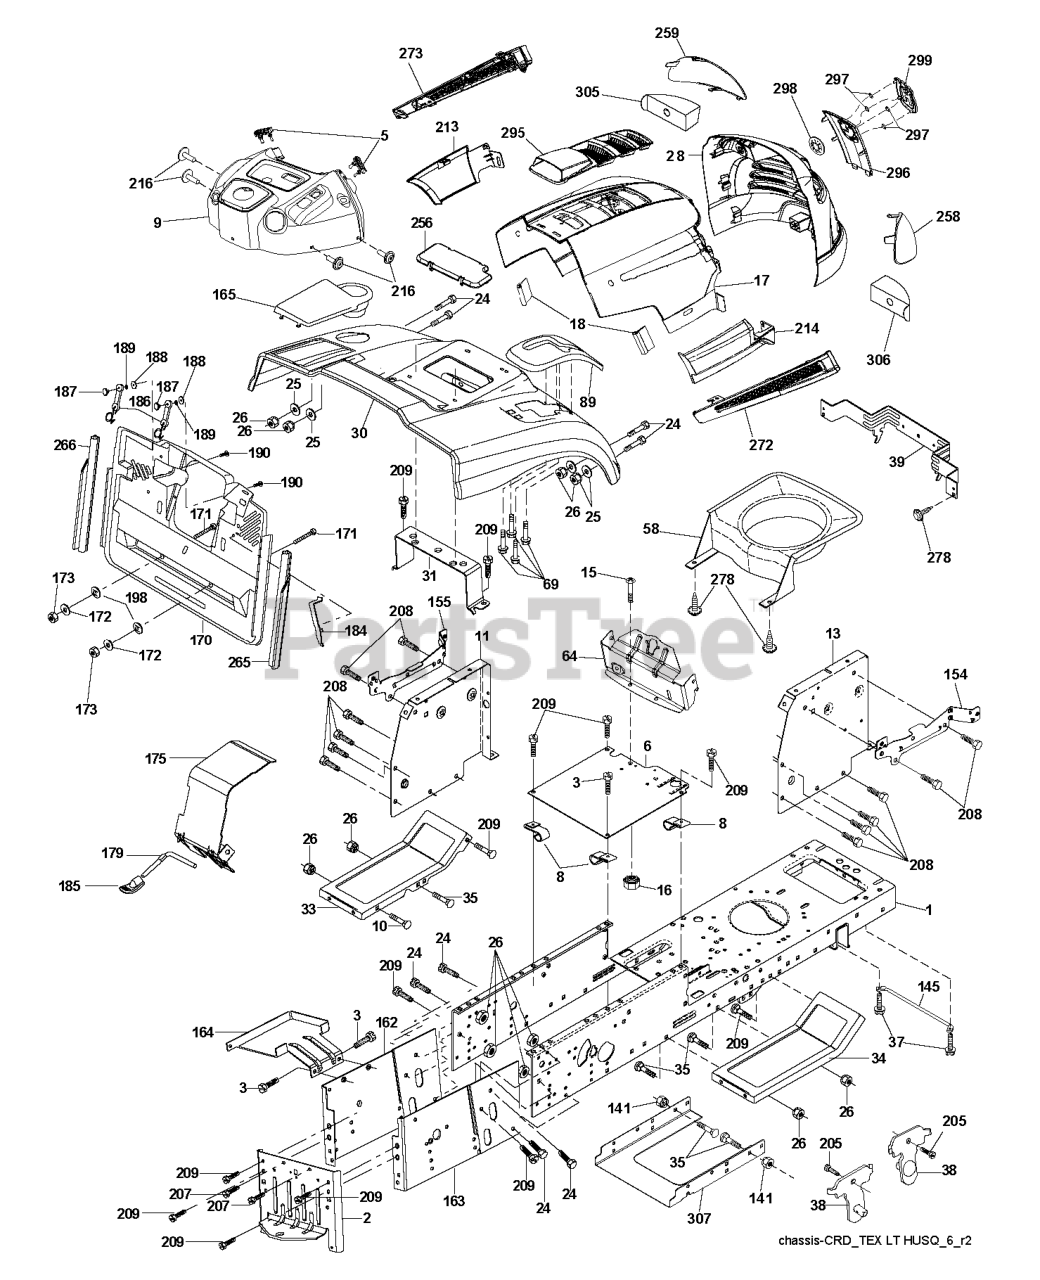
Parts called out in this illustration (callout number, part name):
2	DRAWBAR
3	SCREW 3/8-16X3/4
5	BUMPER DASH
6	PLATE
8	CLIP,INSULATOR
10	BOLT D
11	PANEL.DASH.LH.LTX
13	PANEL ASM, DASH RH
15	Screw, Machine, Truss Head 5/16-18 UNC x 3/4
16	NUT
17	HOOD.HUSQVARNA.LT.ORANGE
18	BUMPER.HOOD.TEX.HUSQVARNA
24	BOLT
25	WASHER
26	NUT
28	GRILLE.SVC.HUSQVARNA.LT.GREY
30	FENDER.PNT.CRD.MS-668
31	BRACKET SUPPORT FENDER
33	FOOTREST PNT LH
34	FOOTREST PNT RH
35	BOLT
37	Screw 5/16-18 x 1/2 Hex, Self Tapping 5/16-18 x 1/2
38	BRACKET ASM PIVOT MOWER REAR
39	BRACKET PIVOT
69	SCREW.HI-LO.CONSOLE
141	NUT LOCK FLG 3/8-16 UNC
145	ROD.PIVOT.HOOD
162	BRACKET
163	BRACKET EXTEN CHASSIS RH CRD
165	RP.COVER.BATTERY.CRD.GREY
171	BOLT
172	WASHER
175	DOOR TRAP
179	ROD PIVOT FBI
184	BRACKET.ACTUATOR.BAGGER.SRD
186	LATCH ASSY
187	WELDNUT
189	LOCKWASHER #10
190	SCREW
205	SCREW LT
207	SCREW, 5/16-18 X 1/2
208	SCREW 3/8-16X1/2
209	SCREW, 3/8-16X3/4
213	SKIRT SIDE LH
214	SKIRT SIDE RH
216	SCREW HEXWSHR 1/4-20X3/4
256	COVER FENDER CRD
258	LENS.HUSQVARNA LT.RH
259	LENS.HUSQVARNA LT.LH
265	SEALING
266	SEALING
272	VENT SIDE HOOD LH
273	VENT SIDE HOOD RH
278	SCREW.#10 X 0.750.BOS
295	VENT TOP HOOD
296	TRIM
297	CLIP.RETAINER.TINNER.
298	NUT PUSH M
299	RP LOGO
305	INSERT REFLECTIVE
306	INSERT.REFLECTIVE.RH.
